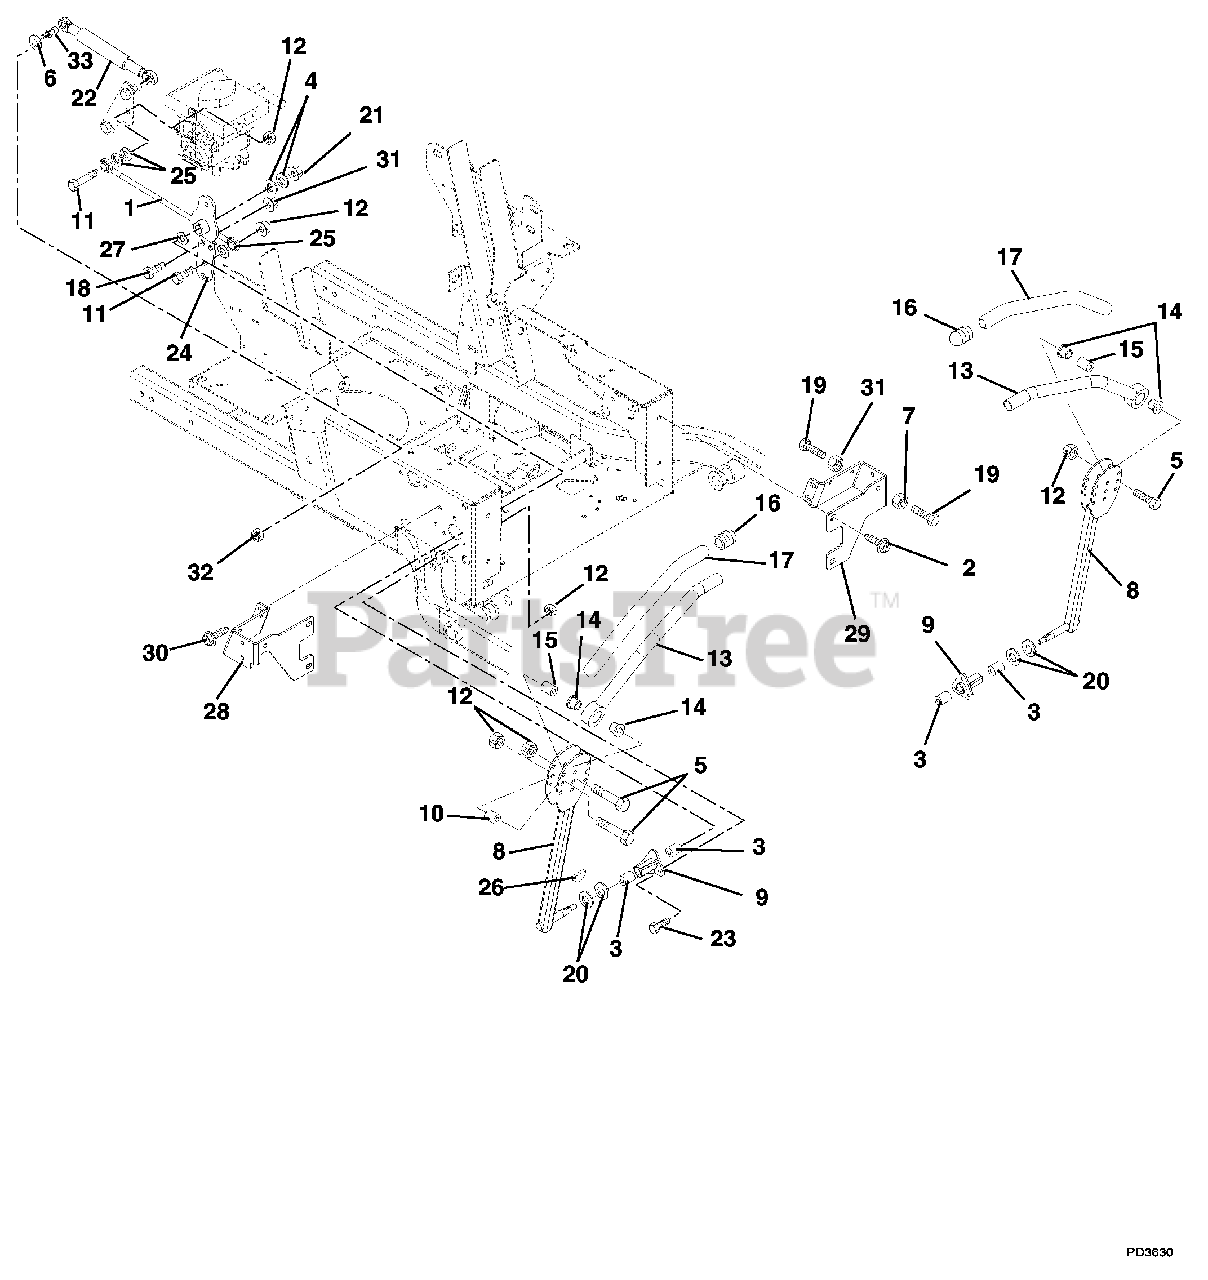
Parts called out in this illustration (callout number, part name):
1	Assembly, Steering Rod
2	Screw, Tapping .38-16 x .75 Hex Washer Head
3	Bushing .625 x .75 x .50
4	Washer, Flat Steel .38 x .875 x .083
5	Bolt, Hex .31-18 x 1.75 Grade 5
6	Washer, Flat Steel .344 x .688 x .065
7	Nut, Hex Jam .375-16
8	Control Arm
9	Housing, Bushing
10	Eccentric
11	Bolt, Hex .31-18 x 1.25 Grade 5
12	Nut, Locking Top Flange .31-18
13	Handle, Left Hand
13	Handle, Right Hand
14	Bushing, Flange Nylon .762 x 1.48 x .44
16	Caplug, Handlebar
17	Grip, Handlebar
18	Bolt, Hex .375-16 x 1.75
19	Bolt, Hex .38-16 x 1.25 Grade 5
20	Washer, Flat Steel .63 x 1.005 x .062
21	Nut, Locking Top Flange .38-16
22	Damper, Control
23	Bolt, Hex .31-18 x .75 Grade 5
24	Arm, Pivot
25	Washer, Locking .31 x .078 Regular
26	Key, Woodruff .13 x .63
27	Wave Washer
28	Stop, Steering - Right Hand
29	Stop, Steering - Left Hand
30	Screw, Tapping .38-16 x .50 Hex Washer Head
31	Nut, Locking Jam Center .375-16
32	Nut, Locking Nylon M8-1.25
33	Stud, Ball
